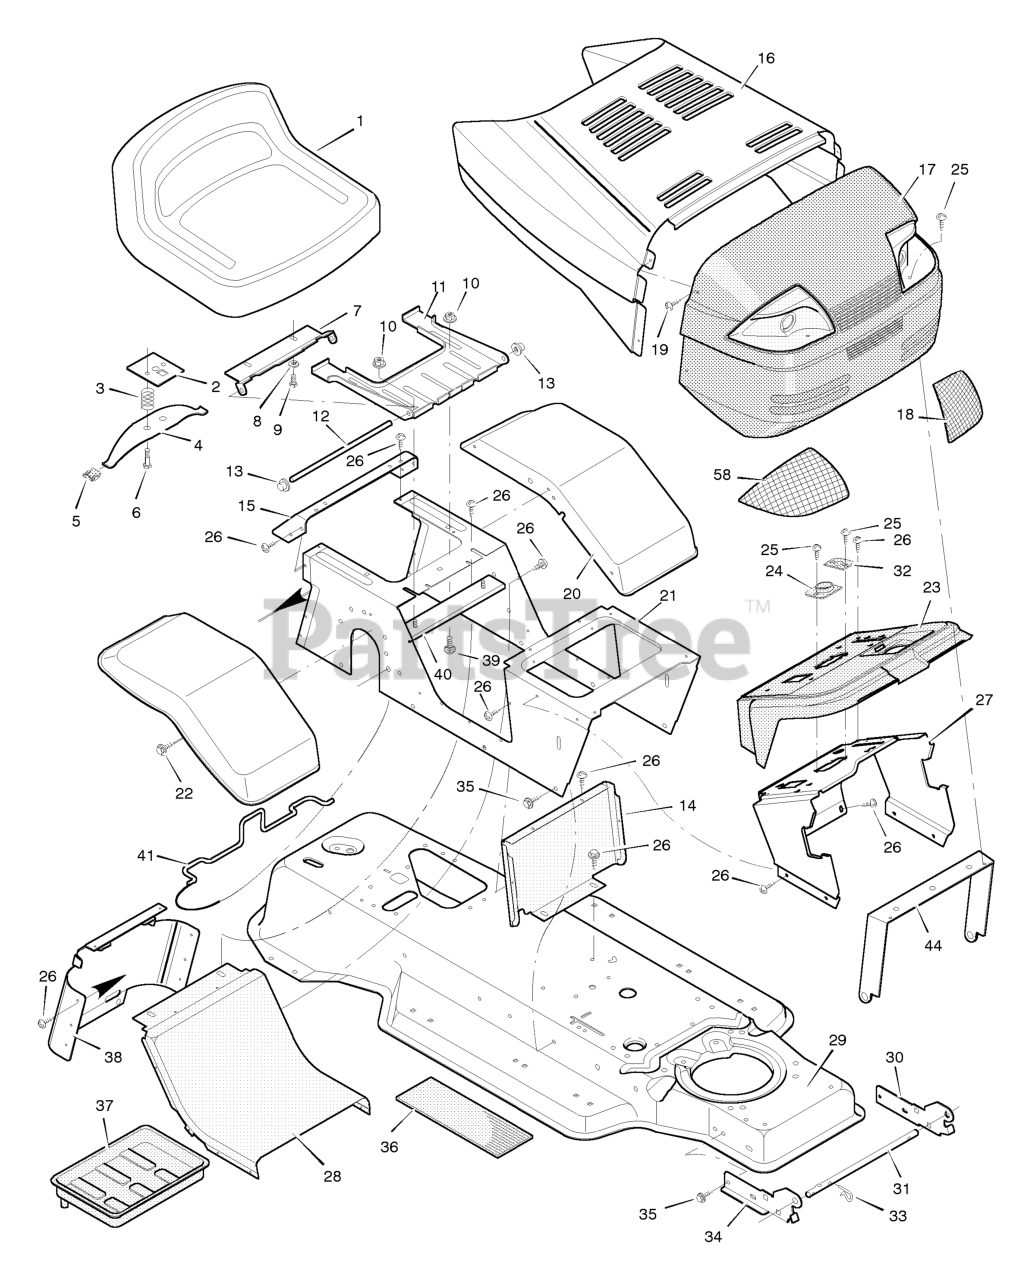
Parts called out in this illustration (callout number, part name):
2	Plate Assembly, Switch
3	Spring, Compression
4	Spring, Seat
5	Glide, Spring
6	Bolt, Shoulder
7	Support, Seat
8	Lockwasher
9	Bolt, Hex
10	Locknut, Flange
11	Bracket, Pivot
12	Rod, Pivot
13	Cap, Push On
14	Insert, Front
15	Fender, Apron
17	Grille Assembly
18	Lens, Left
21	Console Assembly
23	Dash Panel
24	Bearing, Steering
26	Screw
27	Support, Dash
28	Insert, Rear
29	Frame Assembly
30	Bracket, Left Grille
31	Rod, Pivot
32	Bearing
33	Pin, Hair
34	Bracket, Right Grille
37	Tray, Battery
38	Cap, Console
39	Bolt
40	Channel Assembly
41	Clamp, Battery
44	Brace, Grille
45	Washer
46	Bolt, Hex
58	Lens, Right
